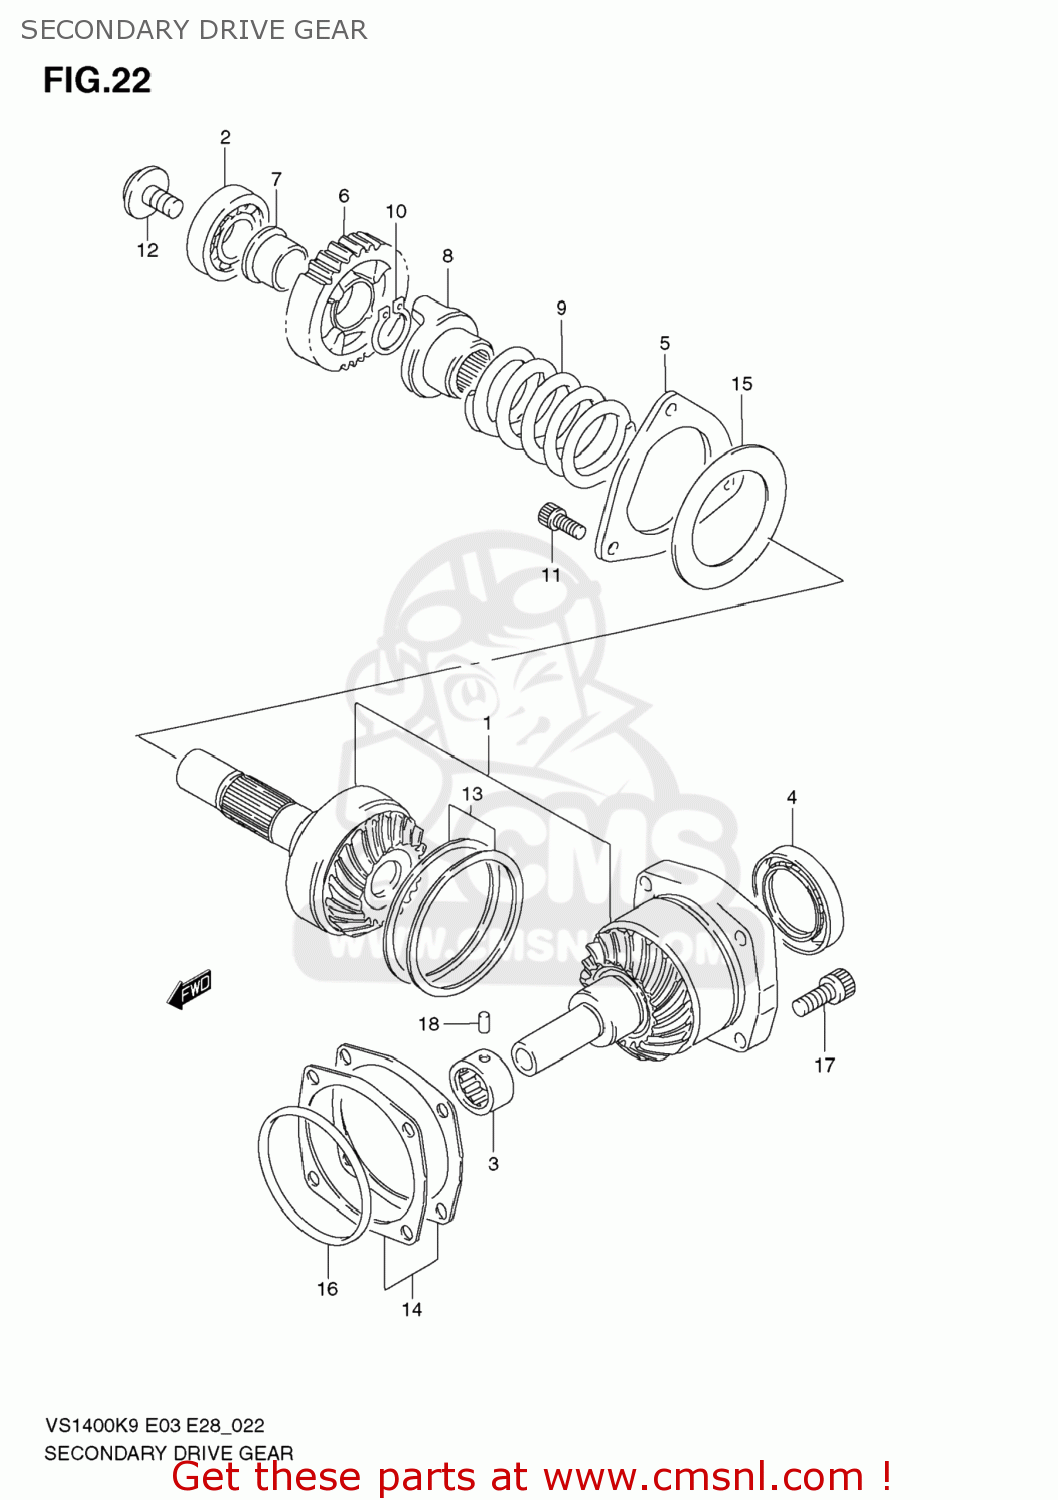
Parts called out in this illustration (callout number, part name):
1	GEAR & HOUSING SET,SECONDARY
2	BEARING(25X62X17)
3	BEARING(20X34X16)
4	SEAL,OIL(44X68X8)
5	STOPPER,SEC DRIVE BEARING
6	GEAR,OVER DRIVING DRIVEN
7	BUSHING,OD DRIVEN GEAR
8	DOG,OUTPUT CAM
9	SPRING
10	CIRCLIP
11	BOLT(8X20)
12	BOLT(14X21)
13	SHIM SET,SEC DRIVE
14	SHIM SET,SEC DRIVEN
15	WASHER(57X90X3)
16	O RING(D:3.7,ID:76.5)
17	BOLT(8X25)
18	PIN
